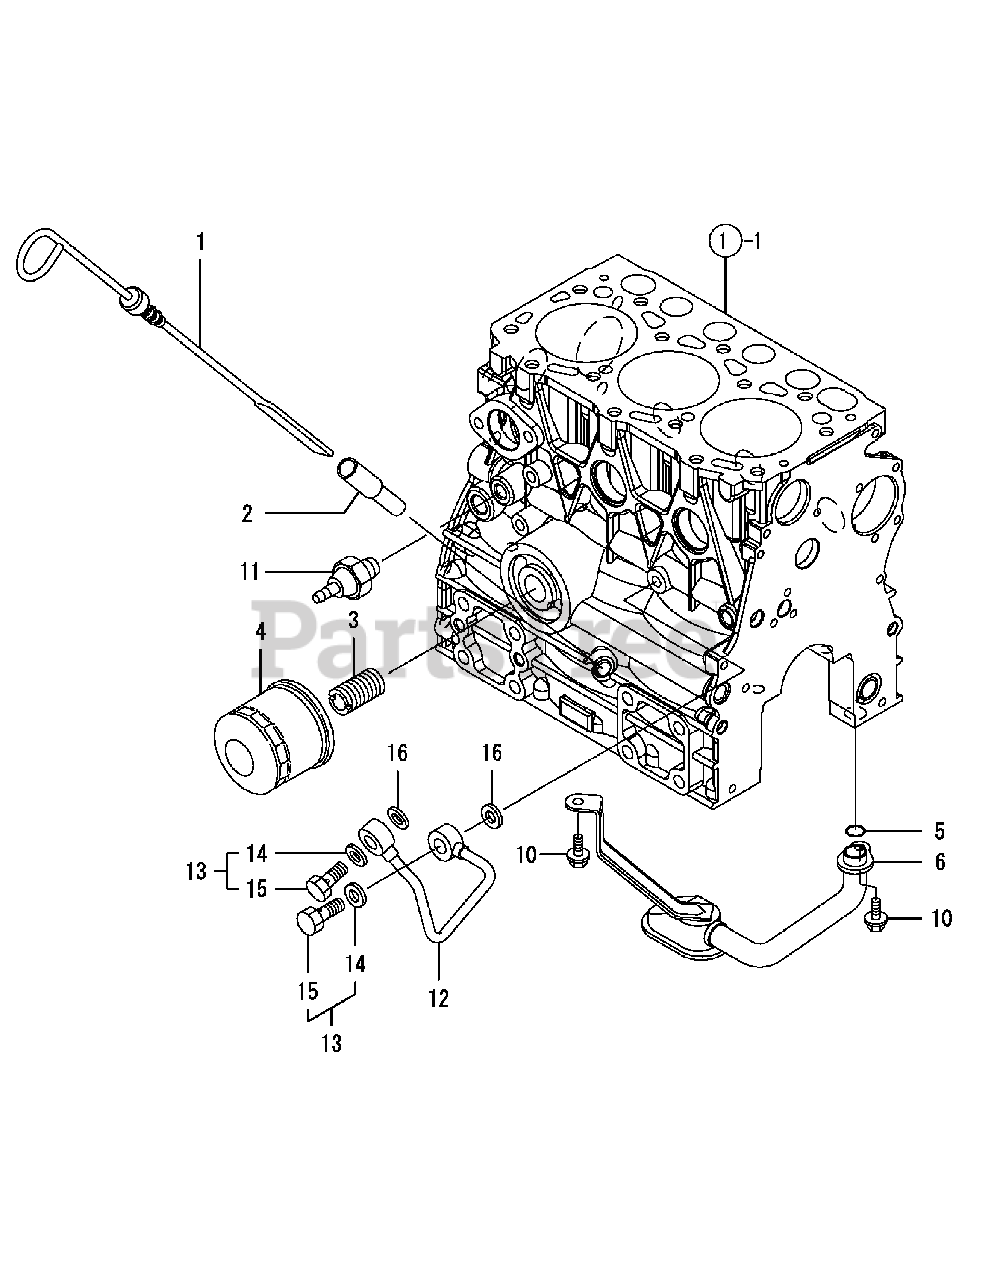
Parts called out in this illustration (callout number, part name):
1	Dipstick, Lub. Oil
2	Guide, Dipstick
4	Filter Assembly, Lub. Oil
6	Pipe Assembly, Lub. Oil
10	Bolt, 6 x 10 Plated
12	Pipe Assembly, Hydraulic
13	Bolt Assembly, Joint
